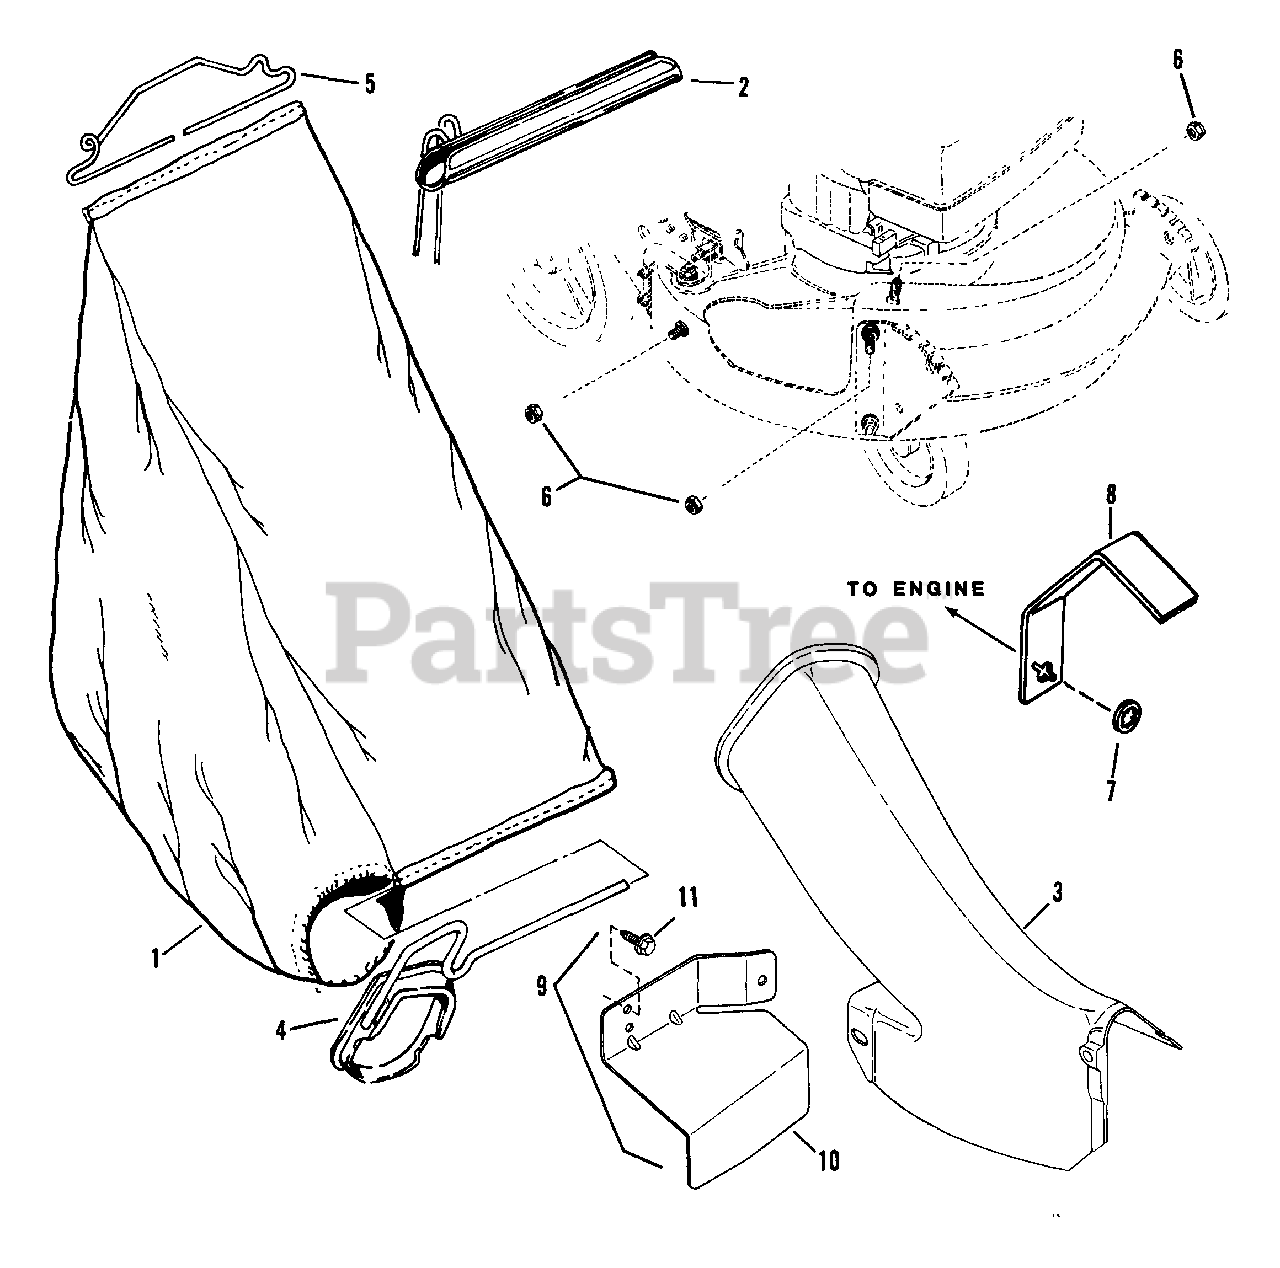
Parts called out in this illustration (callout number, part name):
1	BAG, Grass
2	ASSEMBLY, Rope & Slider
3	ADAPTER, Bag (Replaces #1-9942)
4	CONNECTOR, Bag
5	WIRE, Bag Connector
6	NUT, 5/16-18 Hex Flange Lock
7	WASHER, 1" internal Tooth Lock (used with item 8)
8	SHIELD, Exhaust Heat ('88 Models & Earlier)
9	KIT, Exhaust Shield
10	SHIELD, Exhaust Heat ('89 Models & Later)
11	SCREW, #10-16 x 1/2" Self-Tapping
